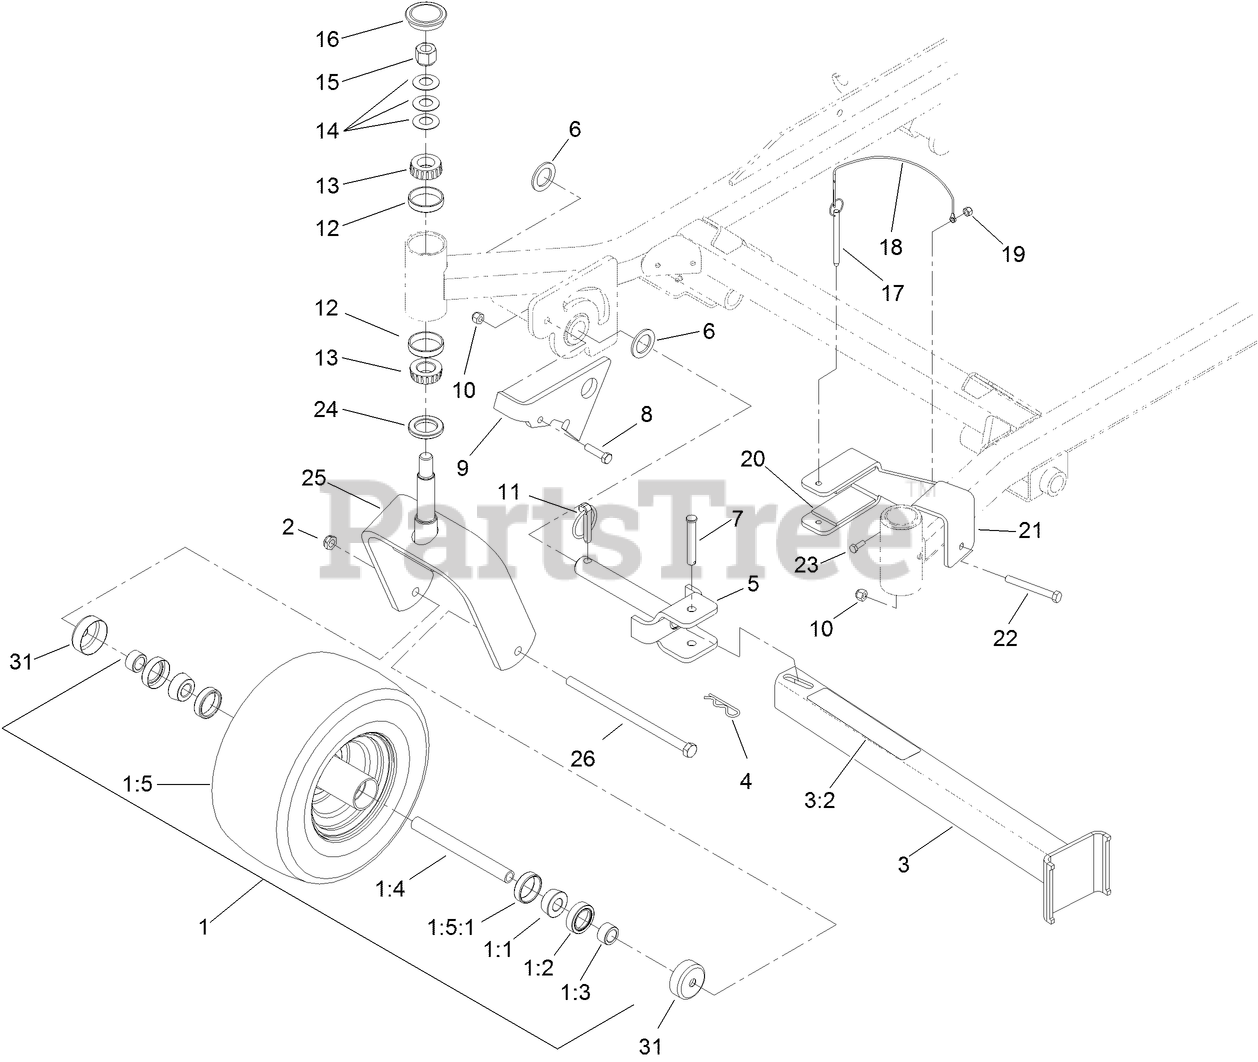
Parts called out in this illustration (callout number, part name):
1	WHEEL AND TIRE ASM
1:1	BEARING-CONE, TAPER
1:2	SEAL-CASTER
1:3	SPACER-NUT
1:4	AXLE-CASTER
1:5	WHEEL AND TIRE ASM
1:5:1	BEARING-CUP
2	NUT-LOCK, NI
3	Leg ASM
3:2	DECAL-Z STAND
4	PIN-HAIR
5	PIN-PIVOT
6	WASHER-THRUST
7	PIN-CLEVIS
8	SCREW-HH
9	BRACKET-LATCH
10	NUT-LOCK, NI
11	PIN-LYNCH
12	BEARING-CUP, TAPERED
13	BEARING-CONE, TAPERED
14	WASHER-BELLVILLE
15	NUT-LOCK, NI
16	CAP-GREASE
17	PIN-HITCH, COTTERLESS
18	LANYARD-NYLON
19	NUT-LOCK, NI
20	Cushion-Rubber
21	BRACKET-CRADLE
22	SCREW-HH
23	SCREW-HH
24	SEAL-GREASE
25	CASTER
26	SCREW-HH
31	GUARD-SEAL
